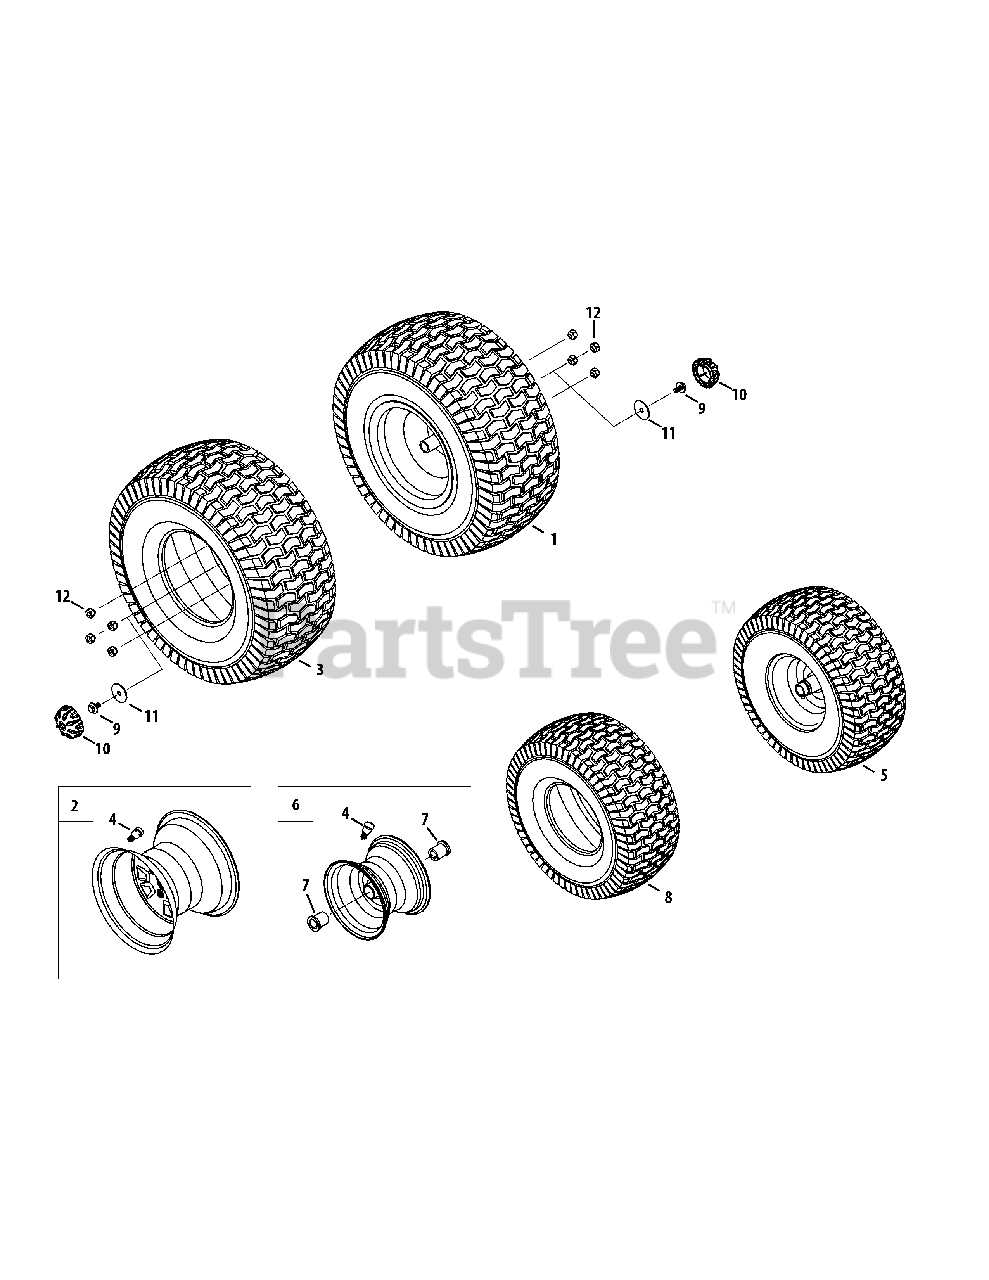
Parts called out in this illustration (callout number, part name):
1	Wheel, Complete, 20 x 8 x 8
2	Rim Ass’y, 8.0 x 7.0 x .750 ID
3	Tire, 20 x 8 x 8 Sq Shoulder
4	Valve, Tubeless Air
6	Rim Ass’y, 6.0 x 4.5, Flnge Bearings
7	Bearing, Flange, .760 ID
8	Tire, 15 x 6 x 6 Sq Shoulder (46")
9	Screw, 5/16-24 x .850
10	Hub Cap
11	Flat Washer, .350 x 1.59 x .062
12	Lug Nut 7/16-14 (54")
